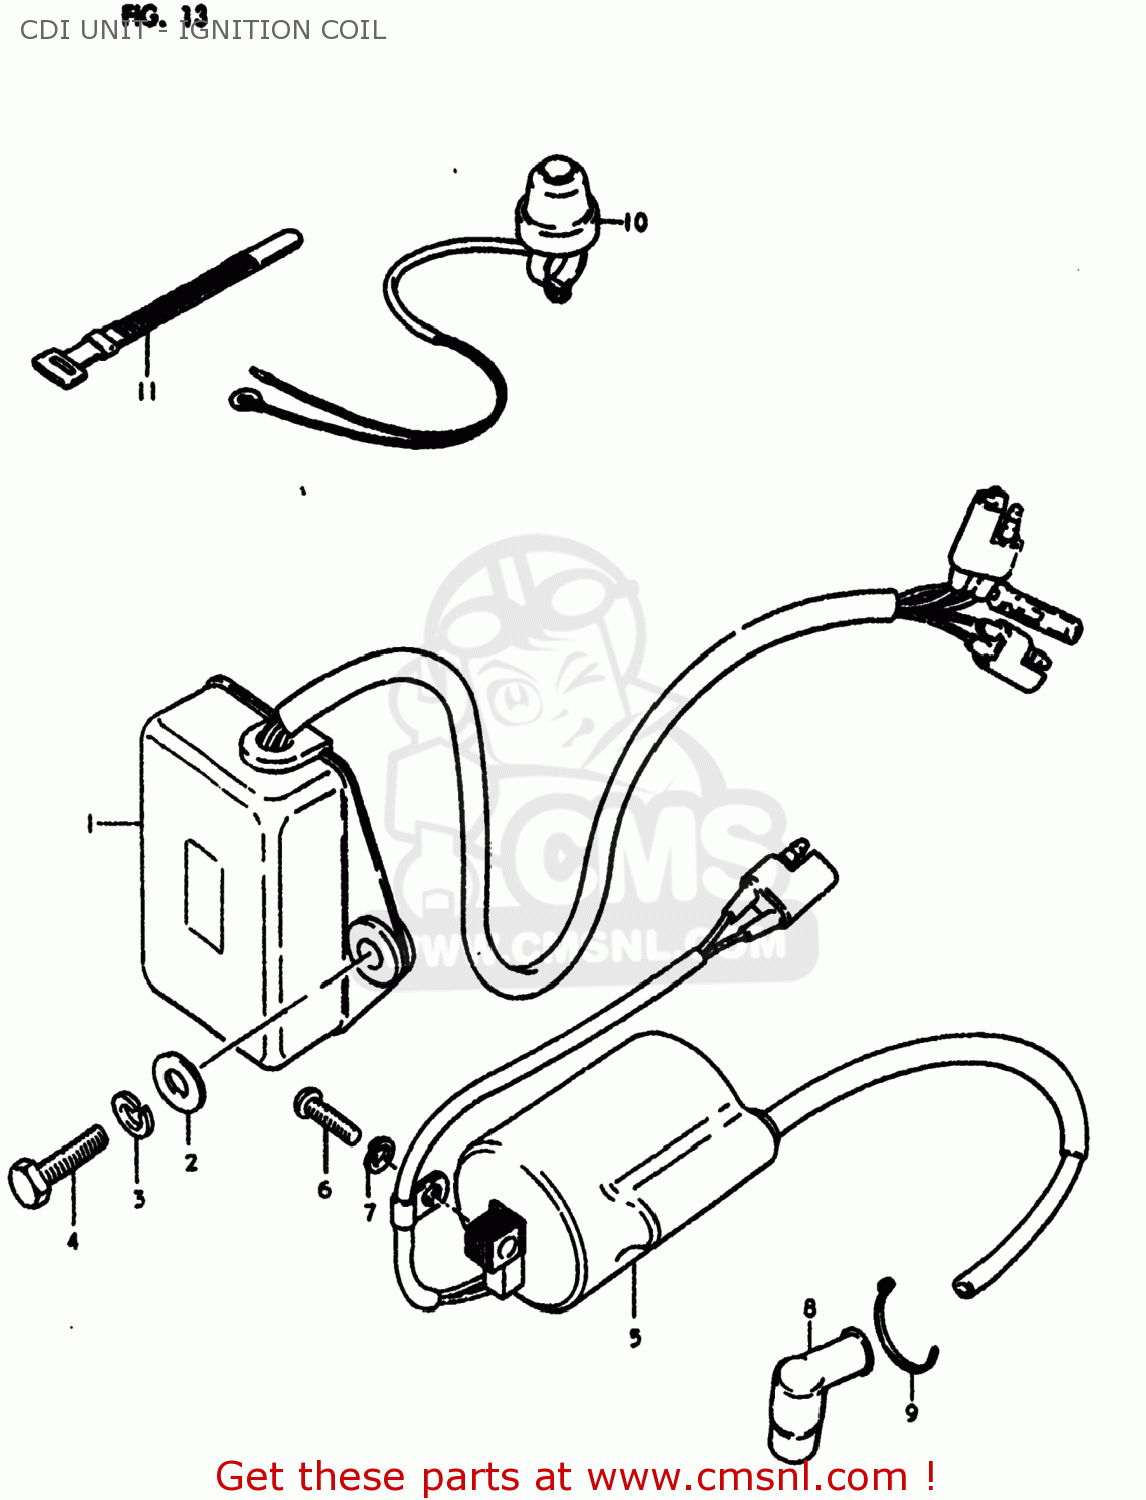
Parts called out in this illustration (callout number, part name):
1	CDI UNIT ASSEMBLY
2	WASHER(6.5X16X1.2)
3	LOCK WASHER
4	BOLT,M6X1X20
5	COIL ASSY,IGNITION
6	SCREW 5X20
7	LOCK WASHER
8	CAP,SPARK PLUG
9	CLAMP
10	SWITCH ASSEMBLY
11	CLAMP(L:120)
